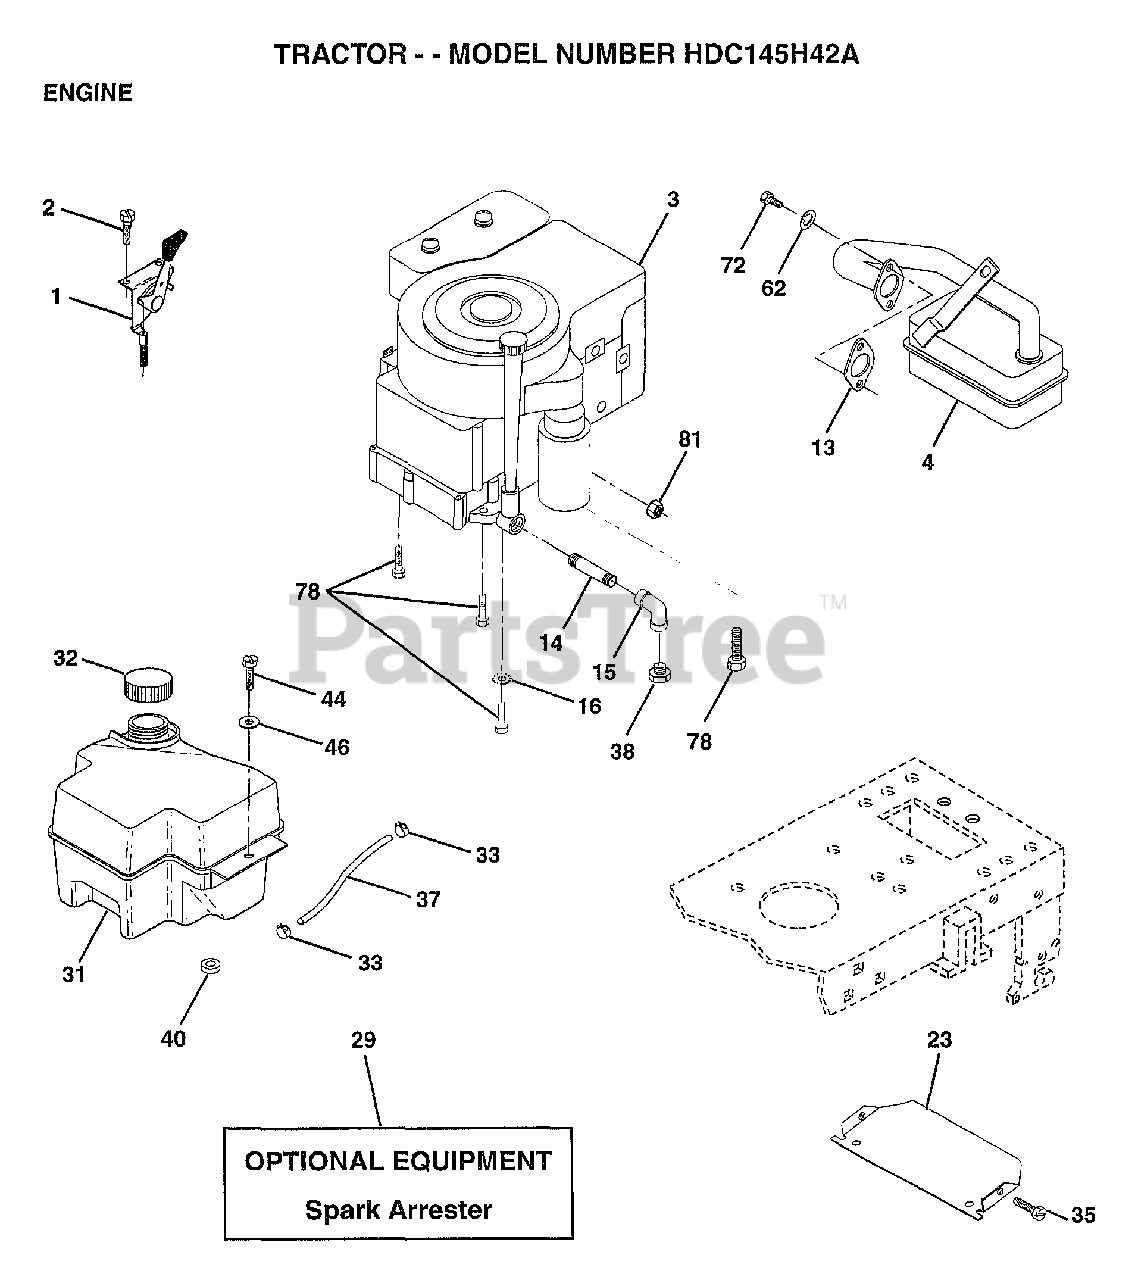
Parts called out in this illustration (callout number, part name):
1	CONTROL THROTTLE
2	SCREW LT
4	MUFFLER
13	GASKET ENG 1 313 LD TIN PLATED
14	PIPE NIPPLE
15	ELBOW
16	LOCKWASHER
23	SHIELD-HEAT
32	CAP ASM FUEL
33	HOSE CLAMP
35	SCREW
37	LINE FUEL
44	SCREW HEX CRT
46	WASHER
62	LOCKWASHER
72	SCREW
78	SCREW
81	NUT
